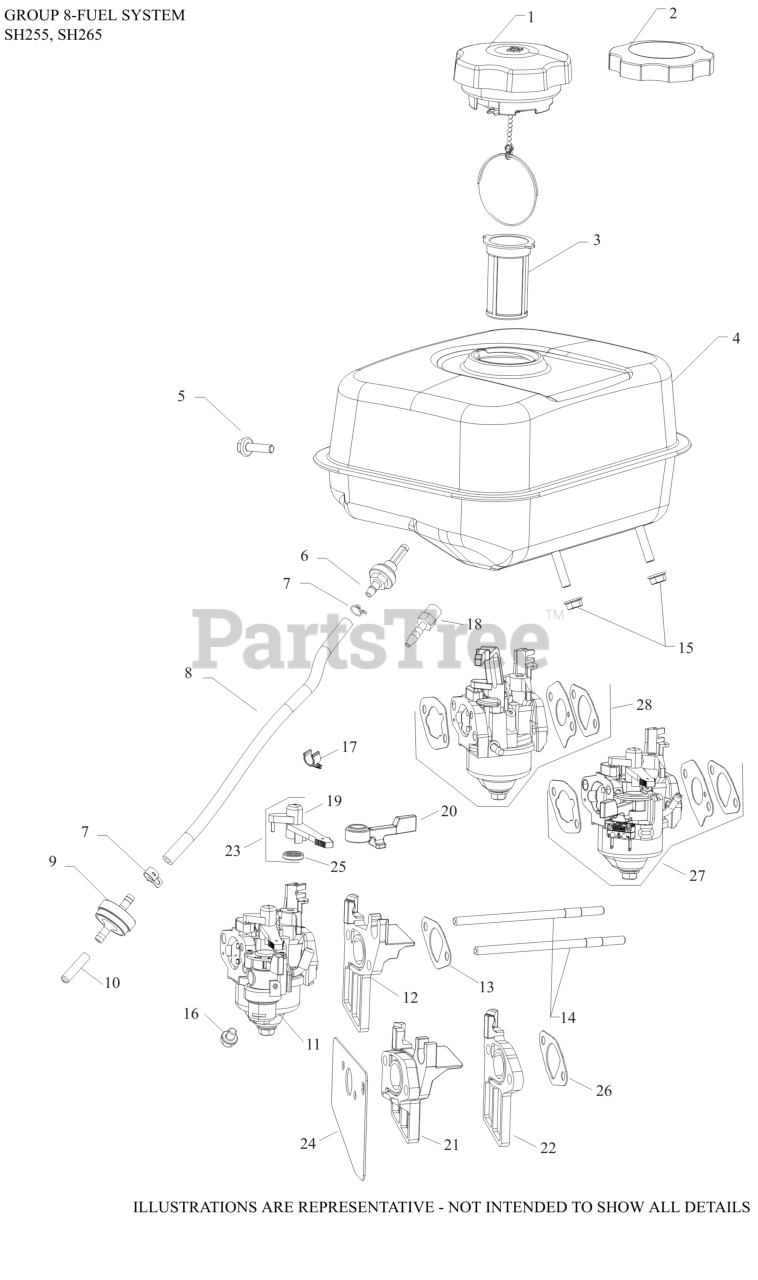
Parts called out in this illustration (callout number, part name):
2	CAP, FUEL TANK
3	FILTER, FUEL TANK
4	KIT, FUEL TANK
5	SCREW, HEX SOCKET HEAD CAP
6	FITTING, FUEL ASSY
7	CLAMP, FUEL LINE
8	LINE, FUEL (10"-CUT TO LENGTH)
11	KIT,CARB (HUAYI)
13	KIT, INTAKE GASKET
14	STUD, CARBURETOR
15	NUT, HEX FLANGE (M6) - USE 14 100 16-S
17	CLIP, FUEL HOSE
22	INSULATOR, CARBURETOR
NI	TOOL, SPARK PLUG WRENCH ASSY
NI	KIT, CARBURETOR REPAIR (HUAYI)
NI	KIT, HIGH ALTITUDE 4000-8000'
NI	KIT, HIGH ALTITUDE ABOVE 8000'
